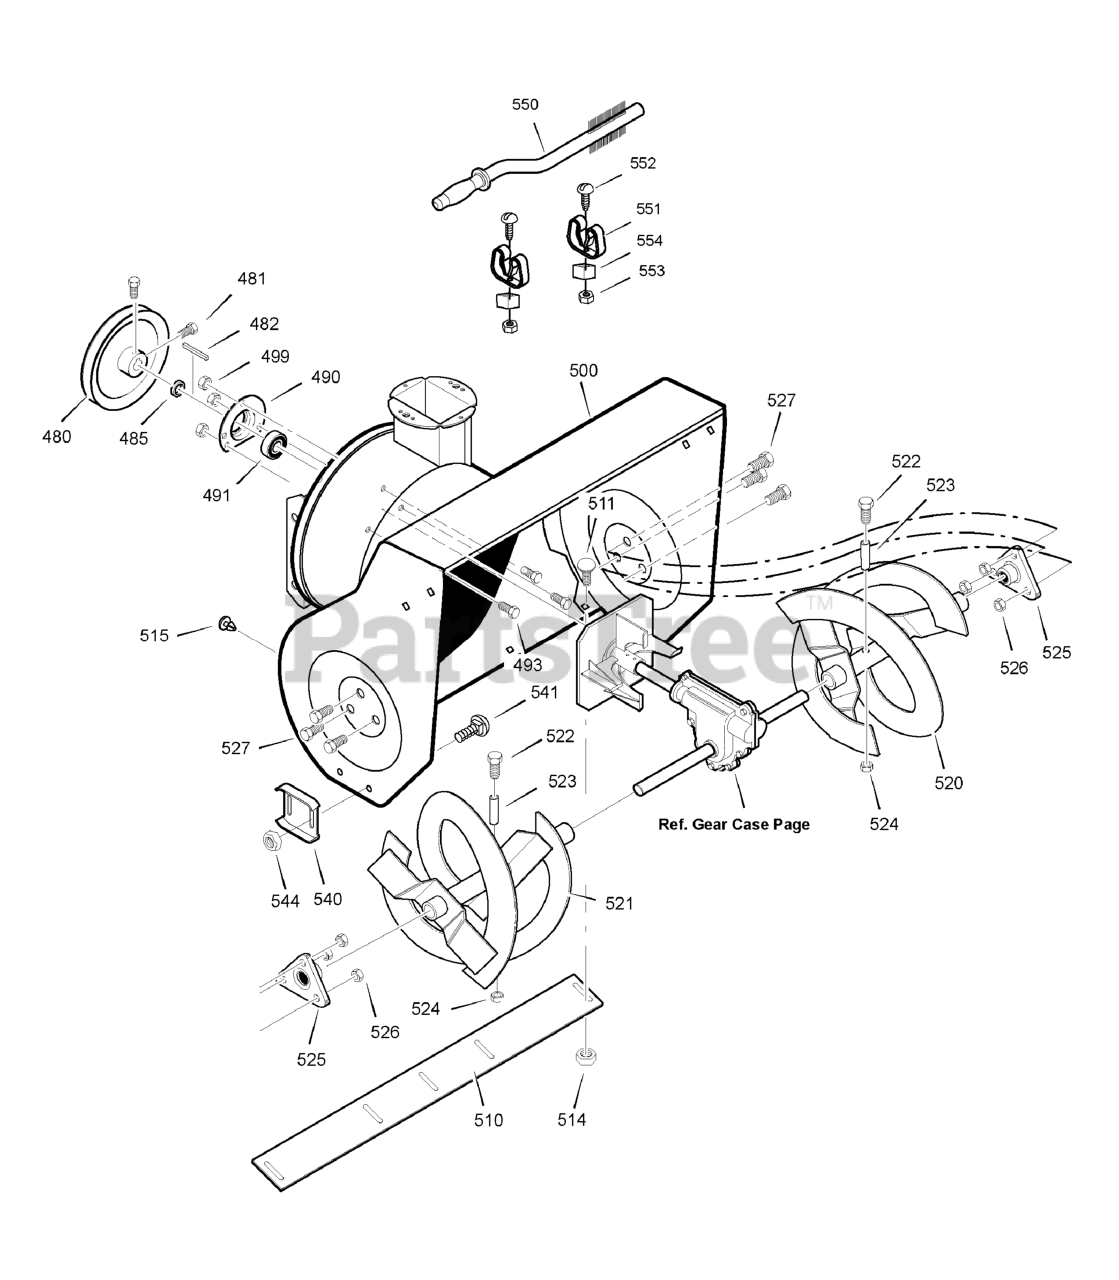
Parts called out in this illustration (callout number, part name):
480	PULLEY, V4L 8.4 X 0.67
481	SCREW, 5/16-18 X 0.63
482	KEY, SQUARE 3/16 X 3/4
485	SPACER, FRICTION PULLEY
490	RETAINER, BALL BEARING
491	BEARING, BALL
493	BOLT, HEX 5/16-18 X .62
499	NUT, 5/16-18 HEXWDFLLK
500	HOUSING, ASSEMBLY
510	BLADE, SCRAPER
511	BOLT, 5/16-18 X 0.62
514	NUT, 1/4-20
515	FASTENER, RACHET BLACK
520	AUGER, ASSEMBLY, LH
521	AUGER, ASSEMBLY, RH
522	SCREW, 1/4-20 X 1.75
523	SPACER, SLEEVE
524	NUT, 1/4-20
525	BEARING, FLANGE
526	NUT, 5/16-18
527	SCREW, 5/16-18 X 0.75
540	SKID, HEIGHT ADJUST
541	BOLT, 5/16-18 X 0.50
544	NUT, 5/16-18
550	BRUSH, CLEANOUT
551	CLIP, RETAINER
552	SCREW
553	NUT
